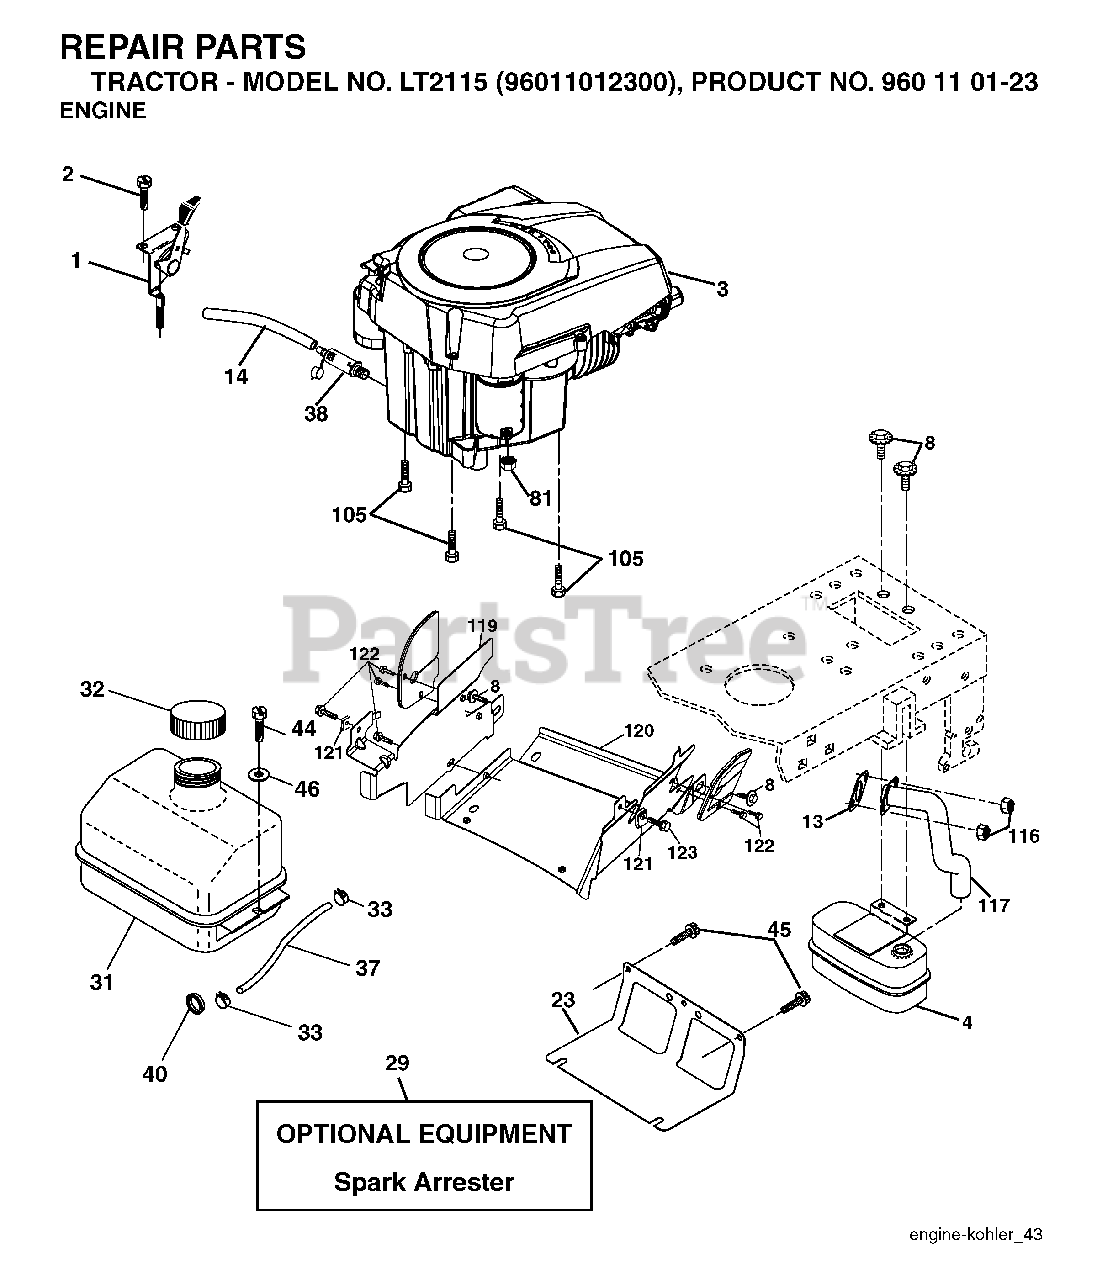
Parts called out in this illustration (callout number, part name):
1	CONTROL.THROTTLE.LT/YT
2	SCREW
4	MUFFLER.SINGLE.CYL.KOHL/B&S
8	BOLT, 5/16-18 X 1 3/4
13	GASKET ENGINE
14	TUBE, DRAIN OIL ASM.
23	SHEILD.BROWNING.DBR.GUARD
29	ARRESTER SPARK (OPTIONAL)
31	TANK FUEL FRONT
32	FUEL CAP
33	HOSE CLAMP
37	LINE.FUEL.20
38	PLUG DRAIN OIL EASY
40	GROMMET T
44	SCREW HEXWSHR 1/4-20X3/4
45	SCREW, 3/8-16X3/4
81	NUT
105	SCREW 3/8-16X1
116	NUT.HEX.FLANGE.TOPLOCK
117	TUBE EXHAUST
122	SCREW.1/4-20X5/8
123	SCREW, 5/16-18 X 1/2
